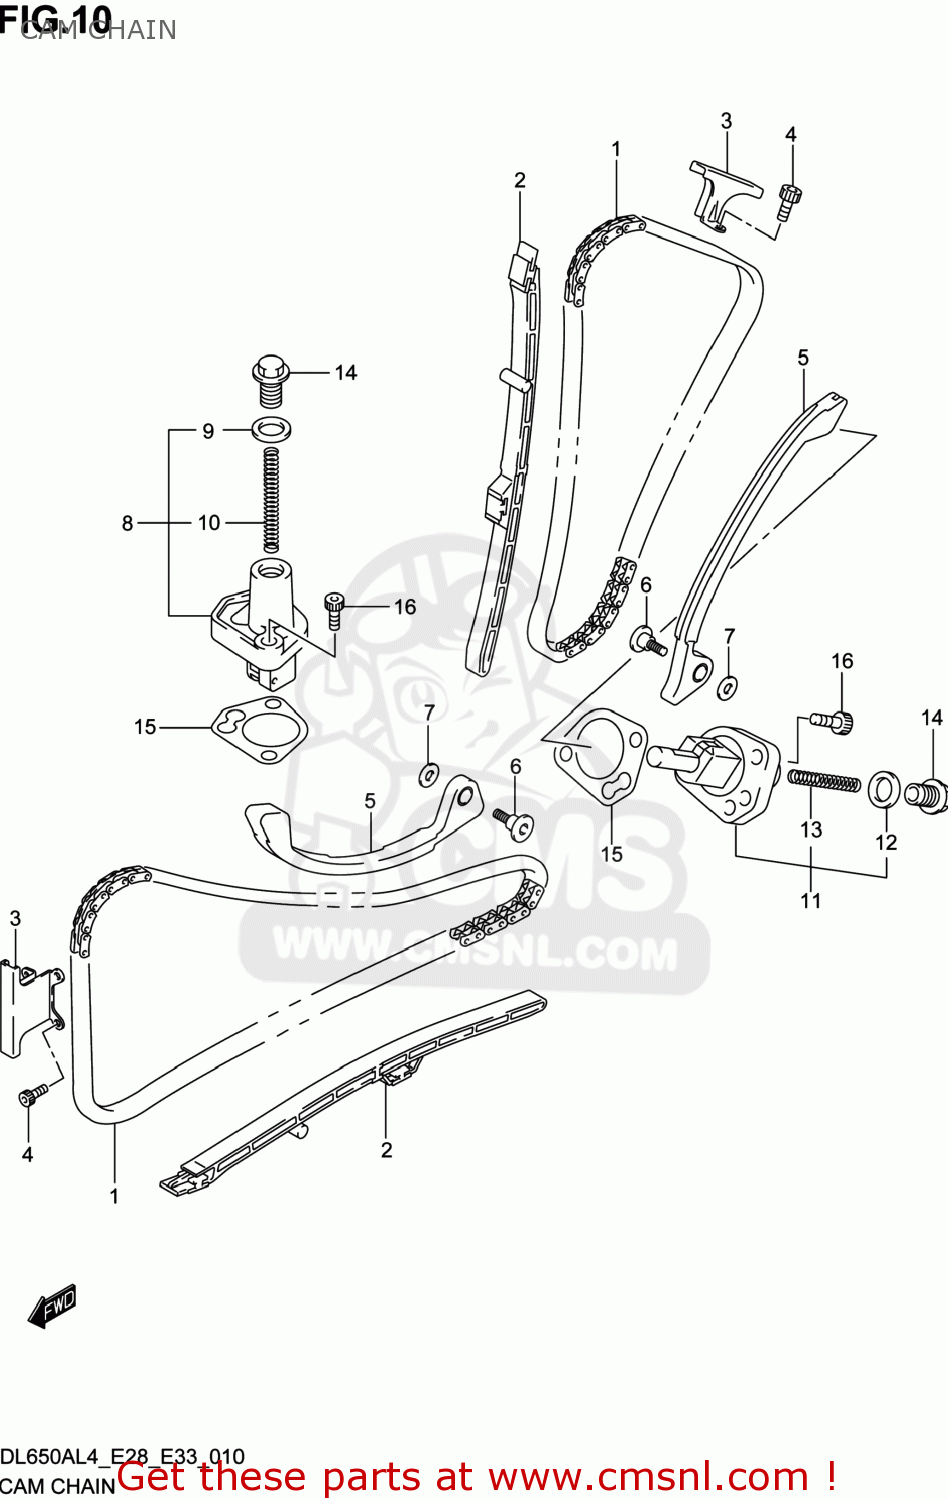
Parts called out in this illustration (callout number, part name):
1	CHAIN,CAMSHAFT DRIVE
2	GUIDE,CAM CHAIN NO.1
3	GUIDE,CAM CHAIN NO.2
4	BOLT
5	TENSIONER,CAM CHAIN
6	BOLT,CAM CHAIN TENSIONER
7	WASHER
8	ADJUSTER ASSY,TENSIONER FR
9	GASKET,TENSIONER ADJUSTER (NAS)
10	SPRING
11	ADJUSTER ASSY,TENSIONER RR
12	GASKET,TENSIONER ADJUSTER (NAS)
13	SPRING
14	PLUG,TENSIONER ADJUSTER
15	GASKET,TENSIONER ADJUSTER (NAS)
16	BOLT
